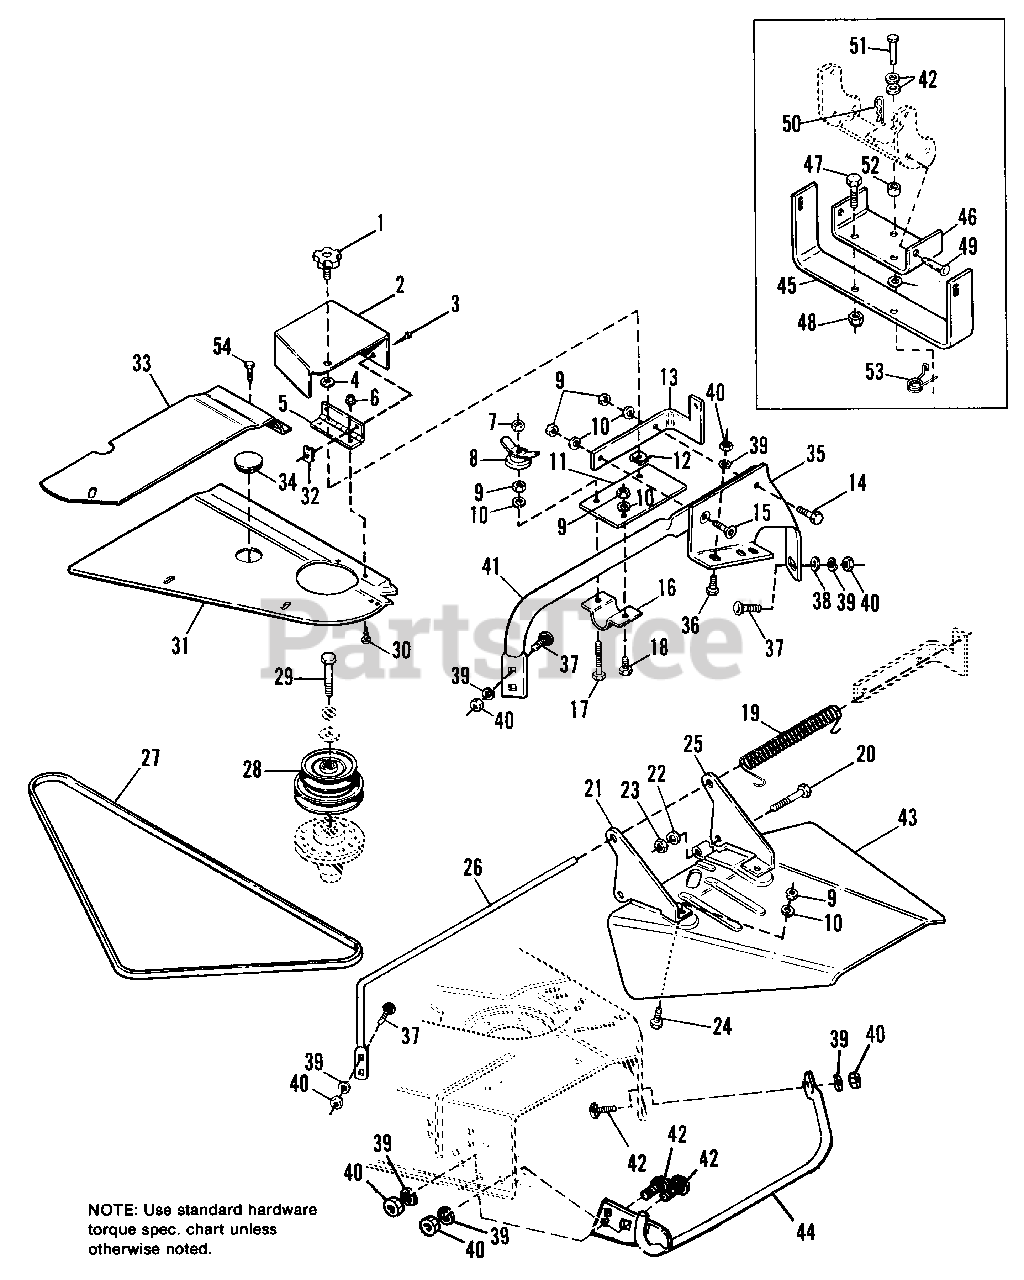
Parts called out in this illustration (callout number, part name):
1	KNOB, Plastic
2	COVER ASSY., Belt (Incl. Ref. Nos. 3, 6 & 7)
3	SCREW, Hex Hd., Thread Forming, #10-1/2
4	PUSHNUT, 5/16
6	NUT, Hex #10-32
7	LOCKNUT, Hex, Full, 5/16-18
8	WING NUT ASSY.
9	NUT, Hex, Full, 5/16-18
10	LOCKWASHER, 5/16
11	CLAMP, Upper
13	PIVOT ASSY., Deflector
14	CAPSCREW, Hex, 5/16-18 x 1-1/4
15	CAPSCREW, Hex, Flat Socket Hd., 5/16-18 x 1-1/4
16	CLAMP, Lower
17	CAPSCREW, 5/16-18 x 2-1/2
18	CAPSCREW, Hex, 5/16-18 x 5/8
19	SPRING, Torsion
20	CAPSCREW, Hex, 7/16-14 x 2-3/4
21	PIVOT BRACKET, L.H.
22	LOCKWASHER, 7/16
23	NUT, Hex, Full, 7/16-14
24	CAPSCREW, Hex, 5/16-18 x 7/8
25	PIVOT BRACKET, R.H.
27	V-BELT (48.7")
28	PULLEY ASSY.
29	CAPSCREW, Hex, 7/16-14 x 2-1/4
30	SCREW, Round Hd., #10-32 x 3/8
31	COVER, L.H.
32	SPEED NUT, #10
33	COVER, L.H.
34	PLUG, Mower Cover
35	BRACKET, Support
36	CAPSCREW, Hex Hd., 3/8-16 x 1
37	CARRIAGE BOLT, 3/8-16 x 1
38	WASHER, Plain, 3/8
39	LOCKWASHER, 3/8
40	NUT, Hex, 3/8-16
41	BRACE, Bracket Support
42	WASHER, Plain, 1/2 x 1 x 1-3/64
43	DEFLECTOR ASSY.
44	STONE GUARD
45	"U" BRACKET
46	ADAPTER, "U" Bracket
47	CAPSCREW, Hex Hd., 1/2-13 x 1-1/2
48	NUT, Hex, Esna Lock, 1/2-13
49	PIN, Round Hd., 7/16 X 1-3/4
50	CLIP, Hairpin
51	PIN, Yoke, 1/2 x 1-7/8
52	SPACER, 1/2 I.D. x 3/4 O.D. x 11/16
53	CLIP, Safety
54	SCREW, Hex, Taptite, 1/4-20 x 3/8
